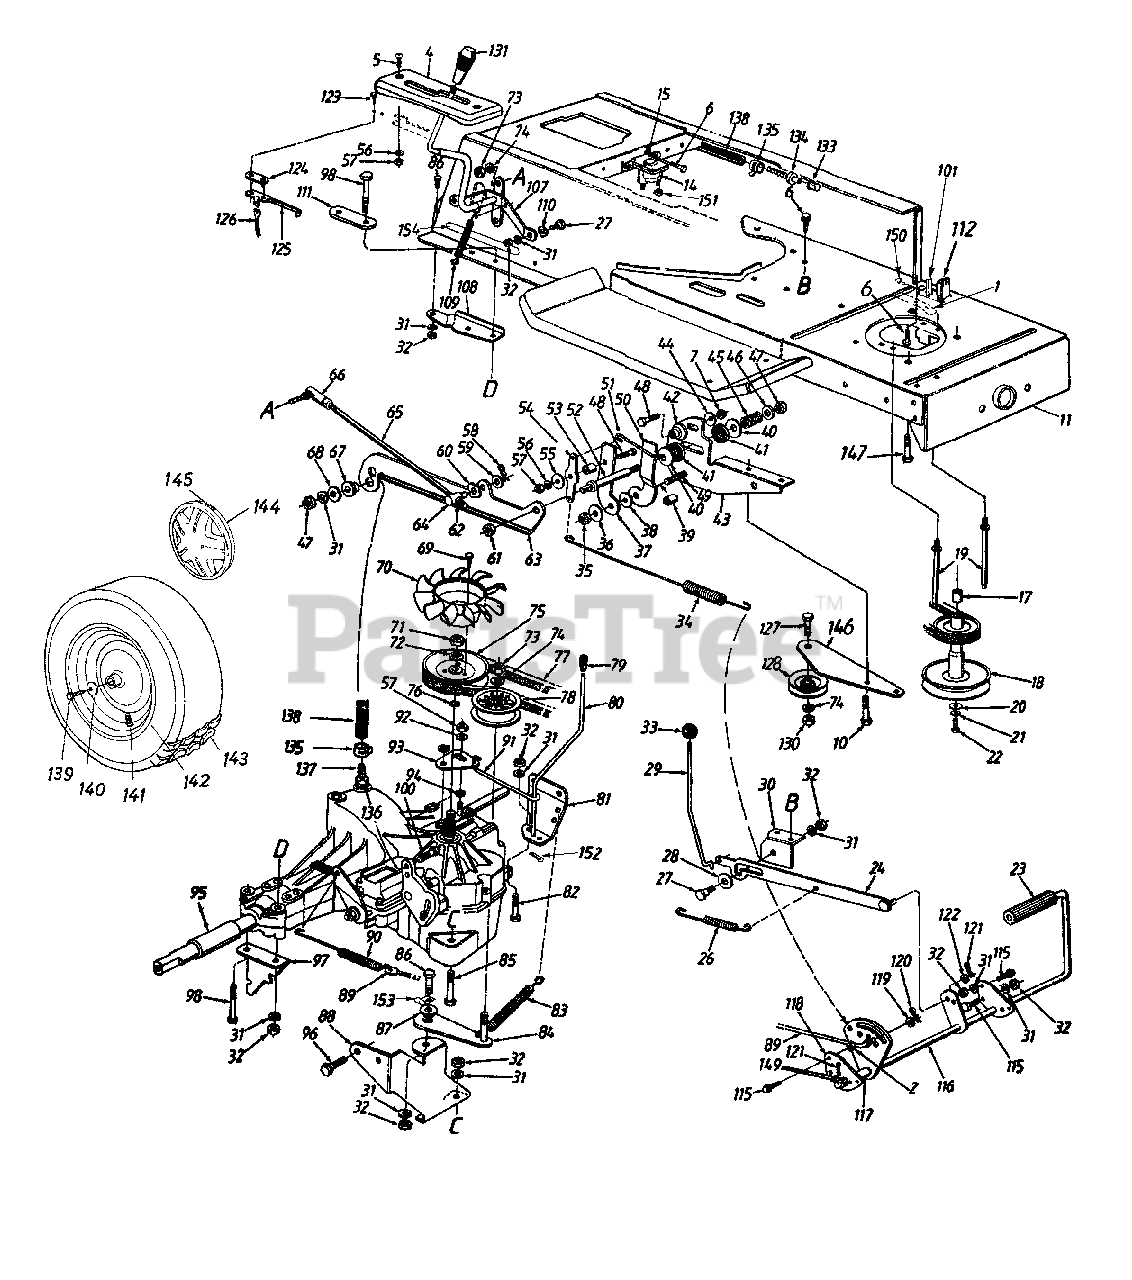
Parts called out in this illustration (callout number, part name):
1	Spring Switch
2	Hex Sems Nut 5/16-18 Thd.
4	Index Bracket
5	Pan Hd. Mach. Scr. 1/4-20 x .75" Lg.
6	Hex Washer TT-Tap Scr. 1/4-20 x .5"
7	Hex Nut 1/4-28 Thd.
10	Hex. Bolt 1/4-20 x .75" Lg.
14	Solenoid
15	Ext. L-Wash. 1/4" I.D.
18	Engine Pulley
19	Belt Guard Stud 4.75" Lg.
20	Fl-Wash. 7/16" I.D. x 1.25" O.D.
21	L-Wash. 7/16" I.D.
22	Hex Bolt 7/16-20 x 1.25" Lg.
23	Foot Pad
27	Shld. Bolt .437" Dia. x .268"
28	Fl-Wash. 7/16" I.D. x 1-3/8" O.D.
29	Lock-up Rod
31	L-Wash. 5/16" I.D.
32	Hex Nut 5/16-18 Thd.
34	Neutral Return Spring
35	Hex Nut 5/16-24 Thd.
36	Fl-Wash. .565 I.D. x 1.12 O.D. x .06
37	Scissor-Flat
38	Fl-Wash. .33" I.D. x 1.25" O.D.
40	Bell-Wash. .4" I.D. x 1.13" O.D.
41	Friction Washer
42	Centering Gauge Spacer
43	Neutral Return Mtg. Brkt.
44	Bell-Wash. .265" I.D. x .75" O.D.
45	Comp. Spring 1.19" Lg.
46	Fl-Washer .344 I.D. x .750 O.D. X .120
47	Hex Nut 5/16-24 Thd.
48	Hex Bolt 1/4-28 x 1" Lg. (Gr. 5)
49	Rib Neck Bolt 5/16-24 x .84" Lg.
50	Scissor-Offset
51	Neutral Return Rod
52	Friction Disc Stud
53	Shld. Spacer
54	Neutral Return Lever
55	Fl-Wash. .265" I.D. x 1" O.D.
56	L-Wash. 1/4" I.D.
57	Hex Nut 1/4-20 Thd.
58	Hairpin Clip
59	Fl-Washer .406" I.D. x .750" O.D. X .63
60	Spring Wash. .39" I.D.
61	Hex L-Nut 3/8-24 Thd.
62	Hex Jam Nut 3/8-24 Thd.
63	Neutral Return Brkt.
64	Ferrule 3/8-24 Thd.
65	Control Rod
66	Ball Joint 3/8-24 Thd.
67	Shld. Spacer .5" Dia. x .27" Lg.
68	Fl-Wash. .349" I.D. x .879" O.D.
69	Hex Tap Scr. #12 x 24 x .82 Lg.
70	Fan
71	Hex Nut 1/2-20 Thd.
72	L-Wash. 1/2" I.D.
73	Hex Nut 3/8-24 Thd.
74	L-Wash. 3/8" I.D.
75	Transmission Pulley
77	"V"-Belt
78	Fl-Idler Pulley 2.75" O.D.
79	Rod End Grip
80	Bypass Control Lever
83	Ext. Spring 6.12
86	Hex Bolt 5/16-18 x 1.00" Lg.
87	Shld. Spacer .5" Dia. x .27" Lg.
90	Ext. Spring
91	Bypass Actuator Rod
92	Fl-Wash. .281" I.D. x .5" O.D.
93	Bypass Adjustment Brkt.
94	External L-Wash. 1/4" I.D.
95	Sleeve .758" I.D. x 1" O.D.
96	Hex. TT-Tap Scr. 5/16-18 x .62"
100	Hex Bolt 5/16-24 x 1" Lg.
101	Hex Wash. Hd. AB-Tap Scr. #10 x .5" Lg.
107	Speed Control Lever Ass'y.
110	Spr-Wash. .445" I.D. x .75" O.D.
112	Safety Switch (Clutch)
115	Hex Hd. Wash. 5/16-18 x .875"
120	Cotter Pin 3/32" Dia.
121	Cotter Pin 1/8" Dia.
122	Fl-Wash. .385" I.D. x .62" O.D.
123	Hex AB-Tap Scr. #8 x .5" Lg.
124	Insulator Nut Plate
125	Spring Switch
126	Extension Wire
127	Hex Bolt 3/8-16 x 1.5" Lg.
128	Idler Pulley
130	Hex Nut 3/8-16 Thd.
134	Plastic Vent
135	Clamp
137	Hose Fitting
138	Fuel Line 20" Lg.
139	Hex Bolt 5/16-24 x .75" Lg.
140	Bell-Wash. .345" I.D. x .88" O.D.
141	Air Valve
149	Fl. Wash. .635 x .930
150	Switch Plate
152	Cotter Pin
154	Reinforcement Bracket
